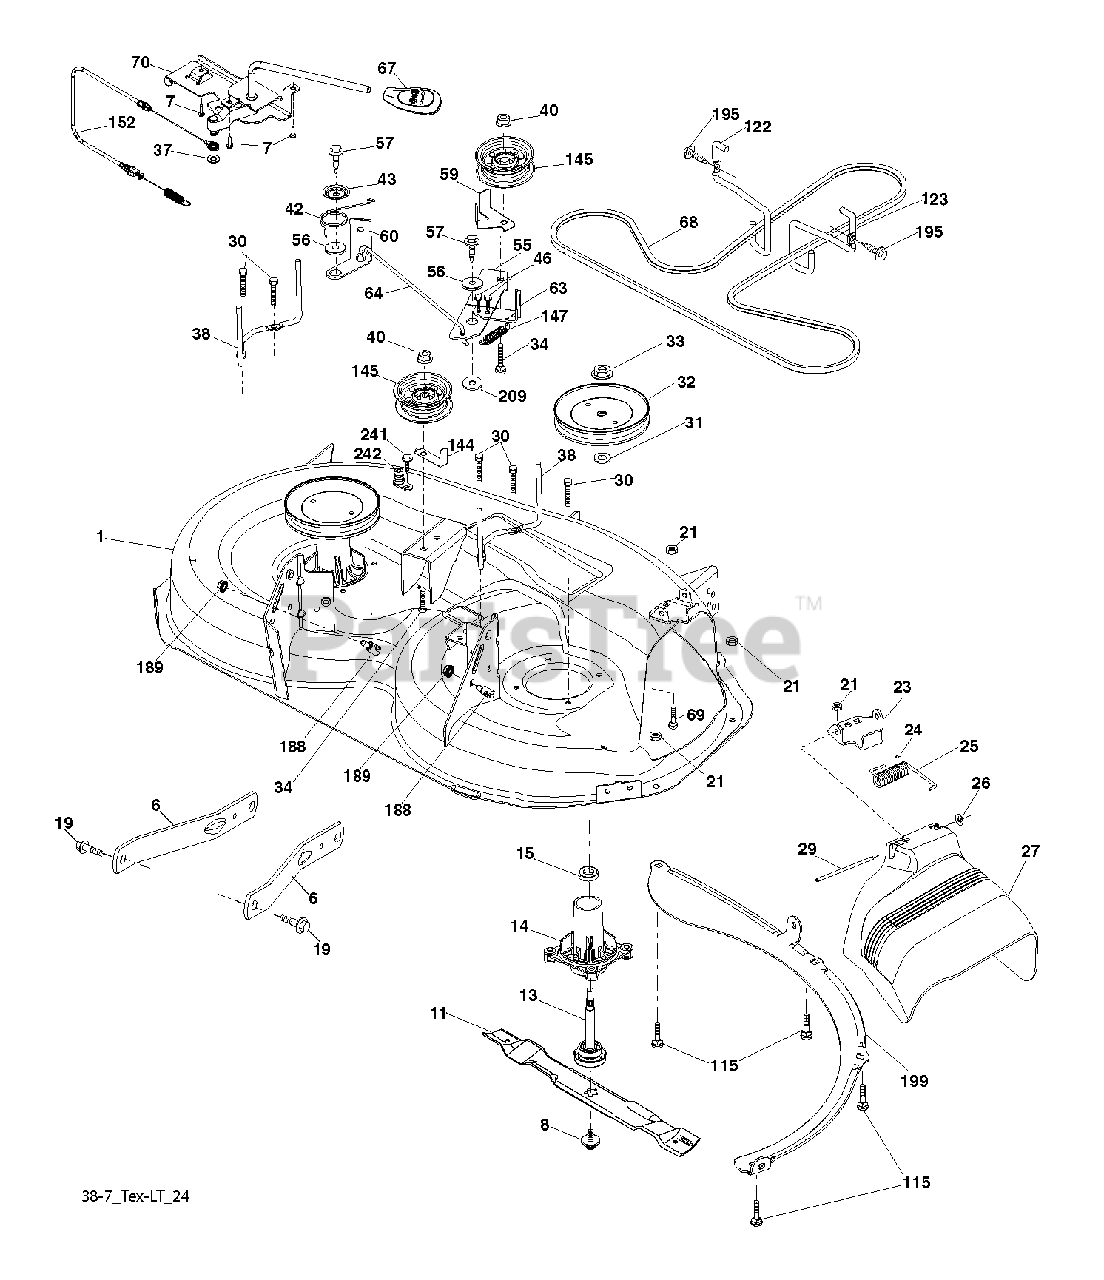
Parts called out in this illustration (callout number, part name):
1	DECK.WELD.38.NGW.TX.W/HOL.GREY
6	ARM.SUSPENSION.MOWER.R
7	SCREW.#10 X 0.750.BOS
8	BOLT.WASHER.ASM.7/16-2
11	BLADE.HI.LIFT.38"
13	SHAFT.ASM.MDRL.N/GREASE.38
14	HOUSING.MANDREL.4PT.
19	BOLT.SHOULDER
21	LOCKNUT
23	BRKT.DEFLECTOR.38"2005+
24	CAP-SLEEVE LT
25	SPRING.TORSION.DEFLECT
26	NUT PUSH M
27	SHIELD.DEFLECTOR.MWR.38-7/97CM
29	ROD.HINGE
30	SCREW, WASHER HEAD
31	WASHER.SPACER.MANDREL
32	PULLEY.MANDREL.5.0.PD.38"
33	NUT.FLANGE.LOCK.TOP
34	BOLT.3/8-16X1.50
37	WASHER
38	KEEPER BELT LH MANDREL
40	NUT LOCK FLG 3/8-16 UNC
42	SPRING.TORSION.BRAKE
43	SRPING.TORSION.RETAINE
46	SCREW.1/4-20X5/8
56	SPACER.RETAINER
57	SCREW 3/8-16X1
59	GUARD, BELT
60	RP ARM.BRAKE.MOWER.38"LH.TEX
63	ARM BRAKE MOWER RH 38"
64	LINK BRAKE
67	HANDLE.CLUTCH.CABLE.LT
69	BOLT
70	CLUTCH.ASM.MANUAL.LT.PRED
115	BOLT
122	KEEPER BELT ENGINE LH
123	KEEPER BELT RH
144	KEEPER BELT
145	PULLEY.IDLER.48"PRIMARY
147	SPRING RETURN
152	CABLE.CLUTCH.MANUAL.
188	STUD.FASTNER.W/ANTI-ROTATE
189	NUT LOCK HEX FLANGE 5/16-18
195	SCREW, 3/8-16X3/4
199	BAFFLE.VORTEX.FRONT.38"
209	WASHER 12/32X2X10GA
241	SCREW.TT.#10-32X.5.3/8.FLANGE
242	PORT.WASHOUT
